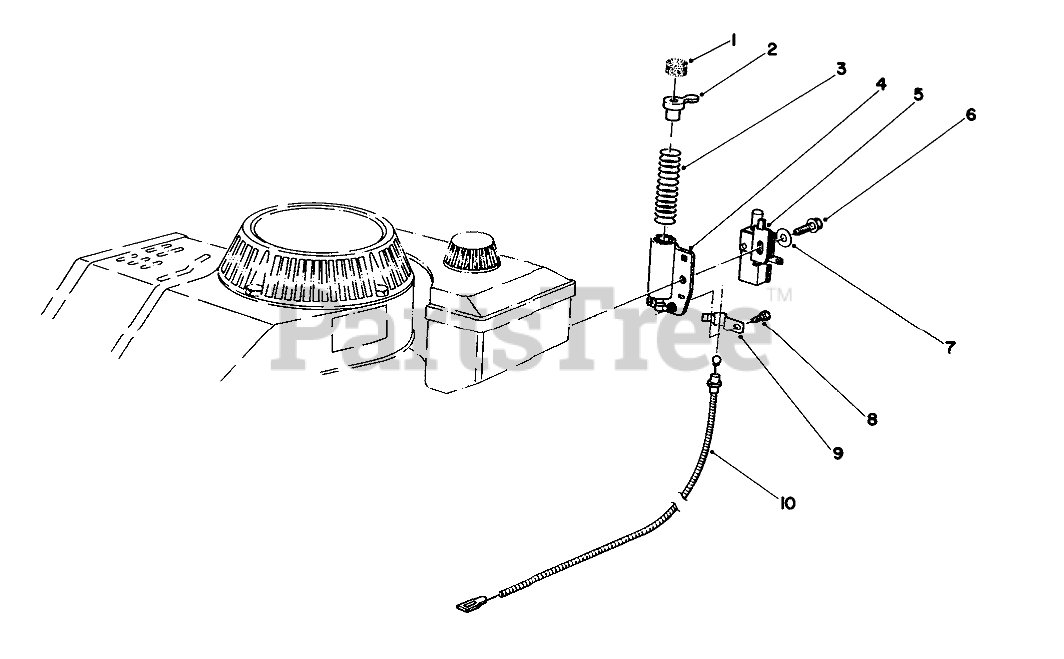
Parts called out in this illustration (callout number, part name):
1	Pad-Friction
2	Plunger & Pad Assembly (Incl. Ref. #1)
3	COMP SPRING
4	TUBE W A
5	PUSH BUTTON SWITCH
6	Screw
7	WASHER-FLAT
8	SCREW
9	CABLE CLAMP
10	BRAKE CABLE
